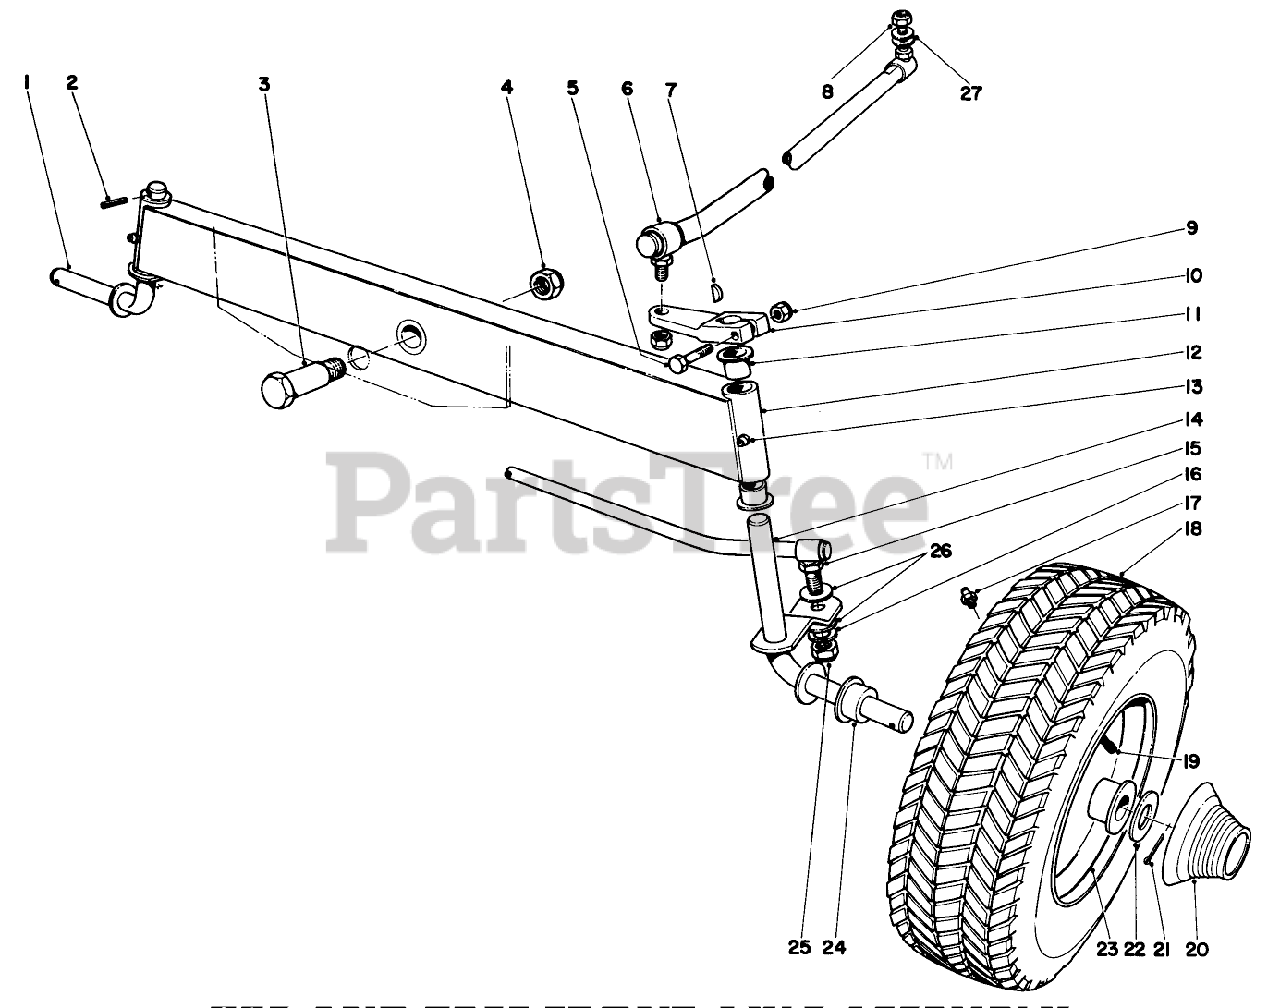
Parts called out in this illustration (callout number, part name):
2	PIN-SPRING
5	SCREW-HH
6	Drag Link
7	KEY-WOODRUFF
10	Arm Drag Link
11	3/4IDX1LG FLANGE BSHG
12	Front Axle Incl. Ref. #11
13	Grease Fitting
14	Spindle L.H.
16	WASHER-LOCK
17	FITTING-GREASE
21	PIN-COTTER
26	WASHER
27	WASHER-FLAT
